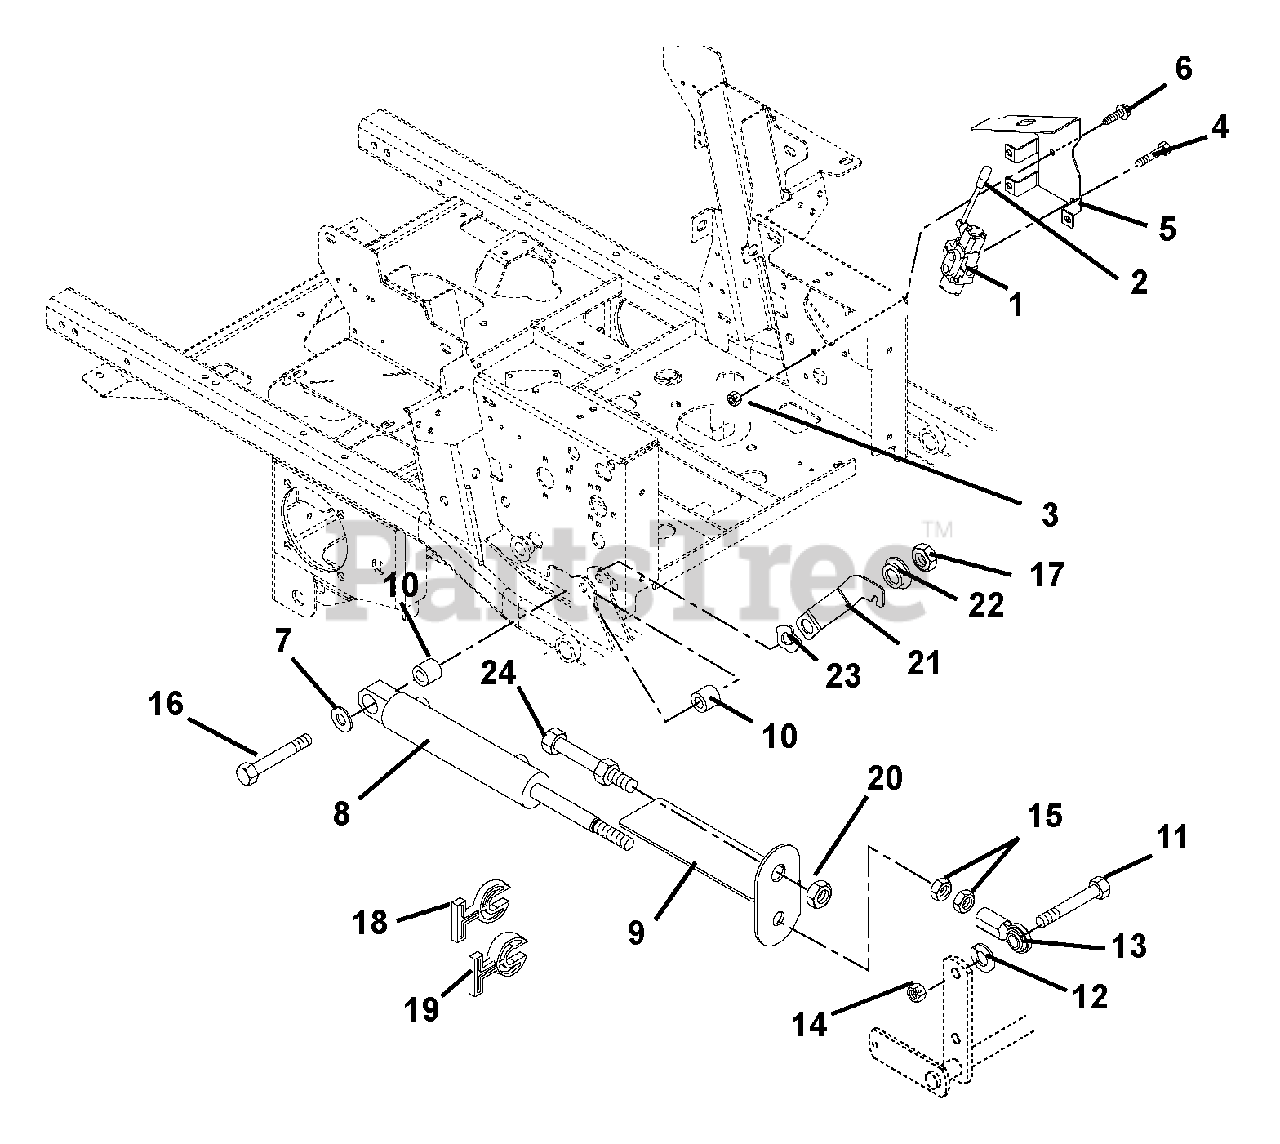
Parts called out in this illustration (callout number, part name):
1	Valve, Hydraulic
2	Knob
3	Nut, Locking Top Flange .31-18
4	Bolt, Hex .31-18 x 2.5 Grade 5
5	Bracket, Valve Mounting
6	Screw, Tapping .38-16 x .50 Hex Washer Head
7	Washer, Flat Steel .515 x 1.625 x .25
8	Cylinder, Hydraulic Lift
9	Strap, Cut Indicator / Guard
10	Bushing .516 x 1.00 x 1.05
11	Bolt, Hex .62-11 x 2.25 Grade 8
12	Washer, Lock .62 x .156
13	Rod End, Right Hand Female .625
14	Nut, Locking Center .62-11
15	Nut, Jam .625-18
16	Bolt, Hex .50-13 x 3.75 Grade 5
17	Nut, Locking Top Flange .50-13
18	Stop, Cylinder .34 Thick
19	Stop, Cylinder .68 Thick
20	Nut, Jam .75-16
21	Latch, Footboard
22	Bushing, Flange .515 x .75 x .275 x 1.12
23	Washer, Wave .076 x 1.12 x .08
